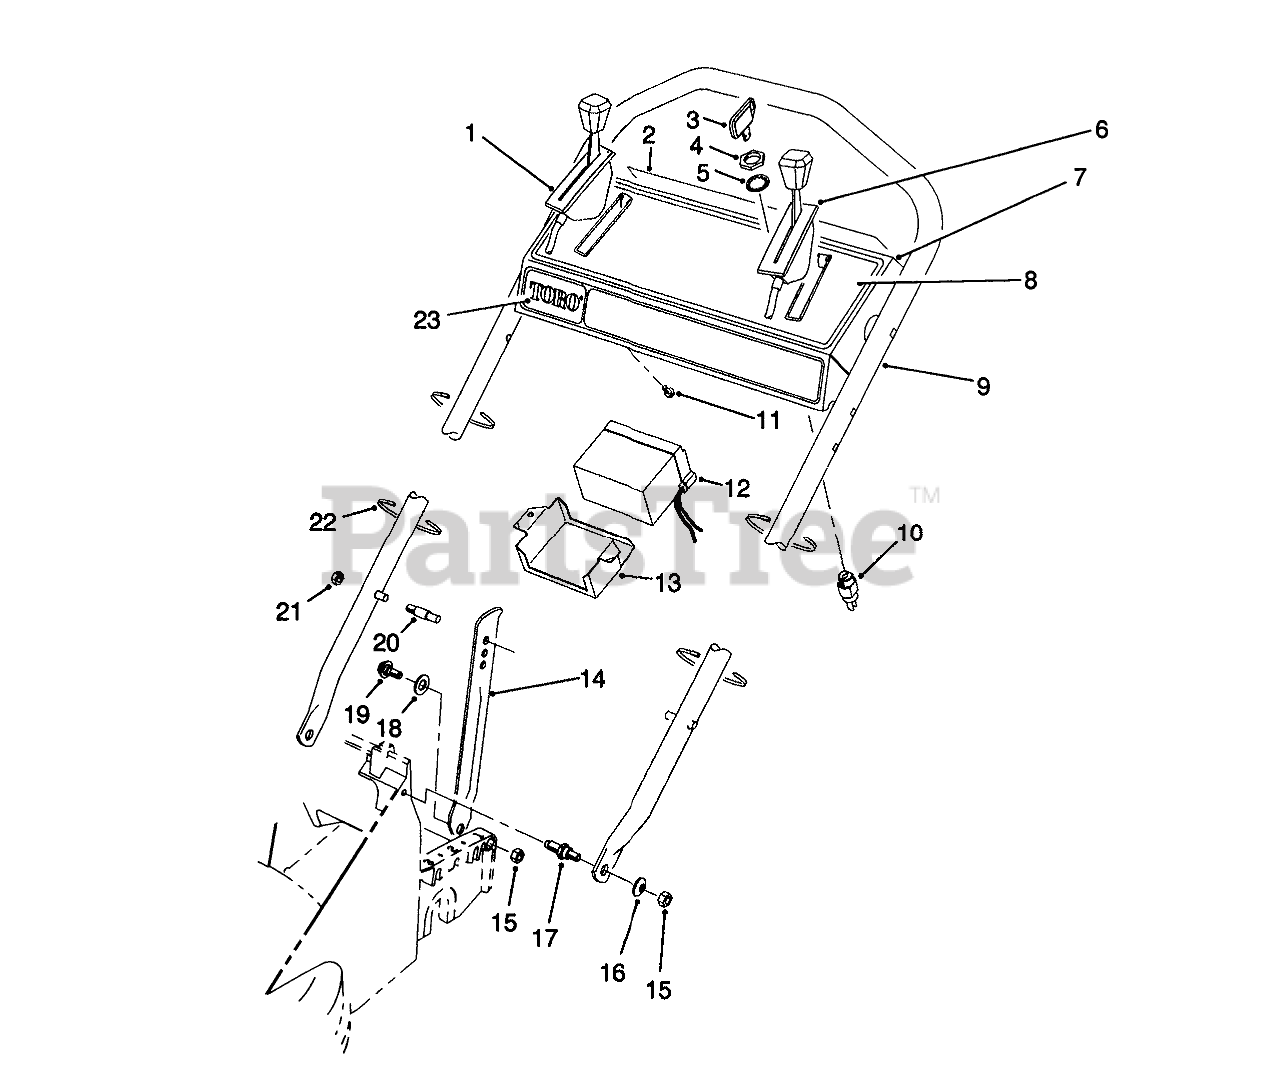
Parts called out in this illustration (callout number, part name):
1	GROUND SPEED CONTROL
2	DECAL - PANEL, REAR
3	KEY-IGNITION
4	NUT-HH
5	WASHER-TOOTH, INTERNAL
6	ControI-Throttle Bend Type #2 Sheath Lg. 44-3/4" Wire Lg. 2-1/2"
7	Panel-Control (Incl. Ref. #8)
8	DECAL - INSTRUCTION
9	HANDLE
10	Switch-Starter (Incl. Ref. #4 & 5)
11	SCREW-HWHTF
12	Battery
13	BATTERY RETAINER
14	HANDLE LATCH
15	NUT-LOCK, NI
16	WASHER-PLAIN
17	SCREW - SHOULDER STUD
18	NYLON WASHER
19	SCREW-SHOULDER
20	HANDLE PIN
21	NUT-LOCK, NI
22	TIE-CABLE
23	DECAL - KEY LECTRIC
